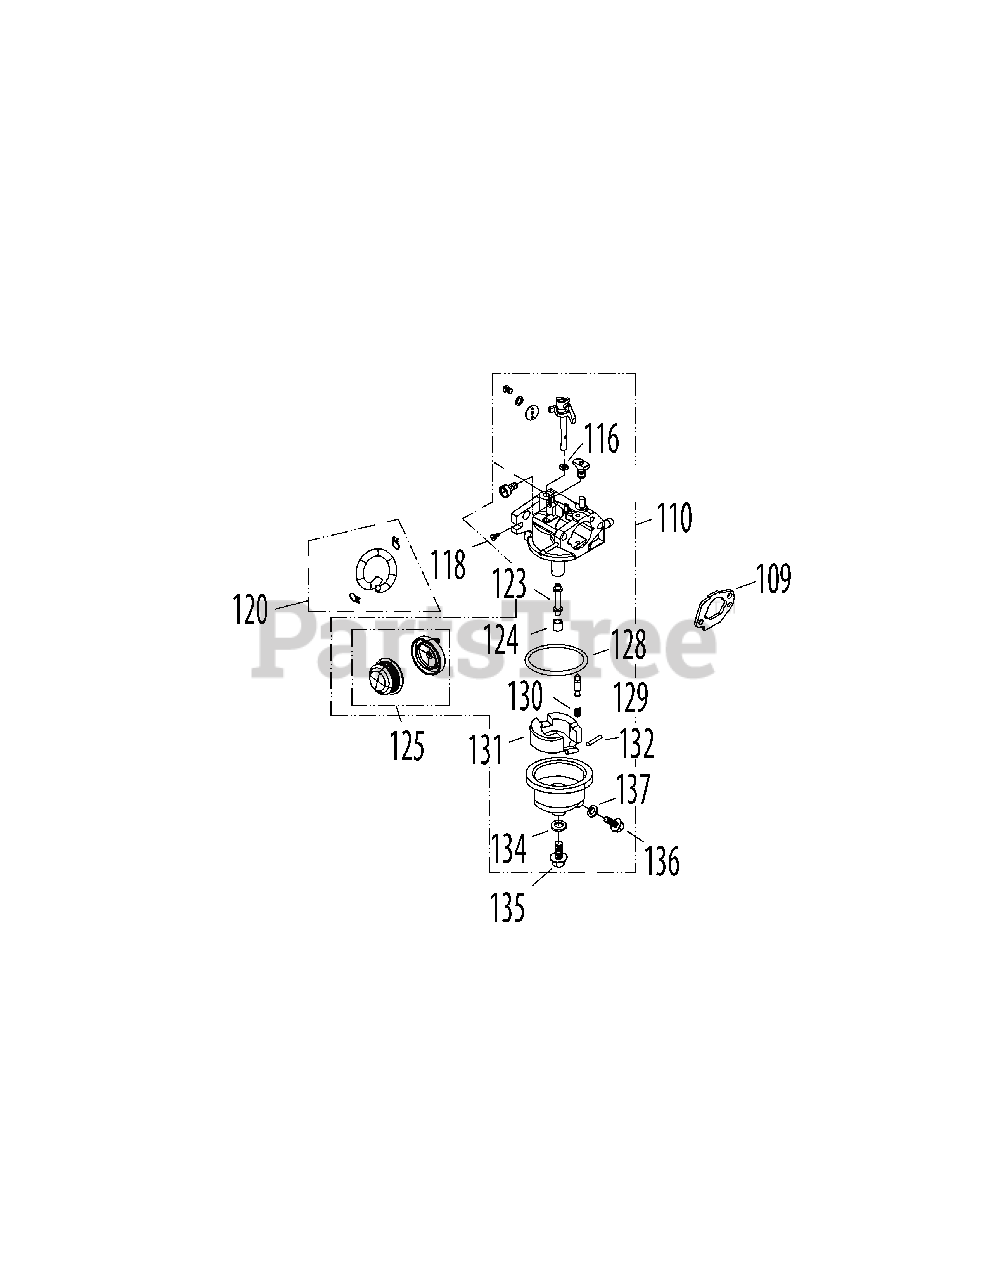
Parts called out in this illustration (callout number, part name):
109	Carburetor Gasket Plate
110	Carburetor Assembly
116	Fiber O-Ring
118	Idle Speed Adjusting Screw
120	Primer Hose Assembly
125	Primer Bulb only
